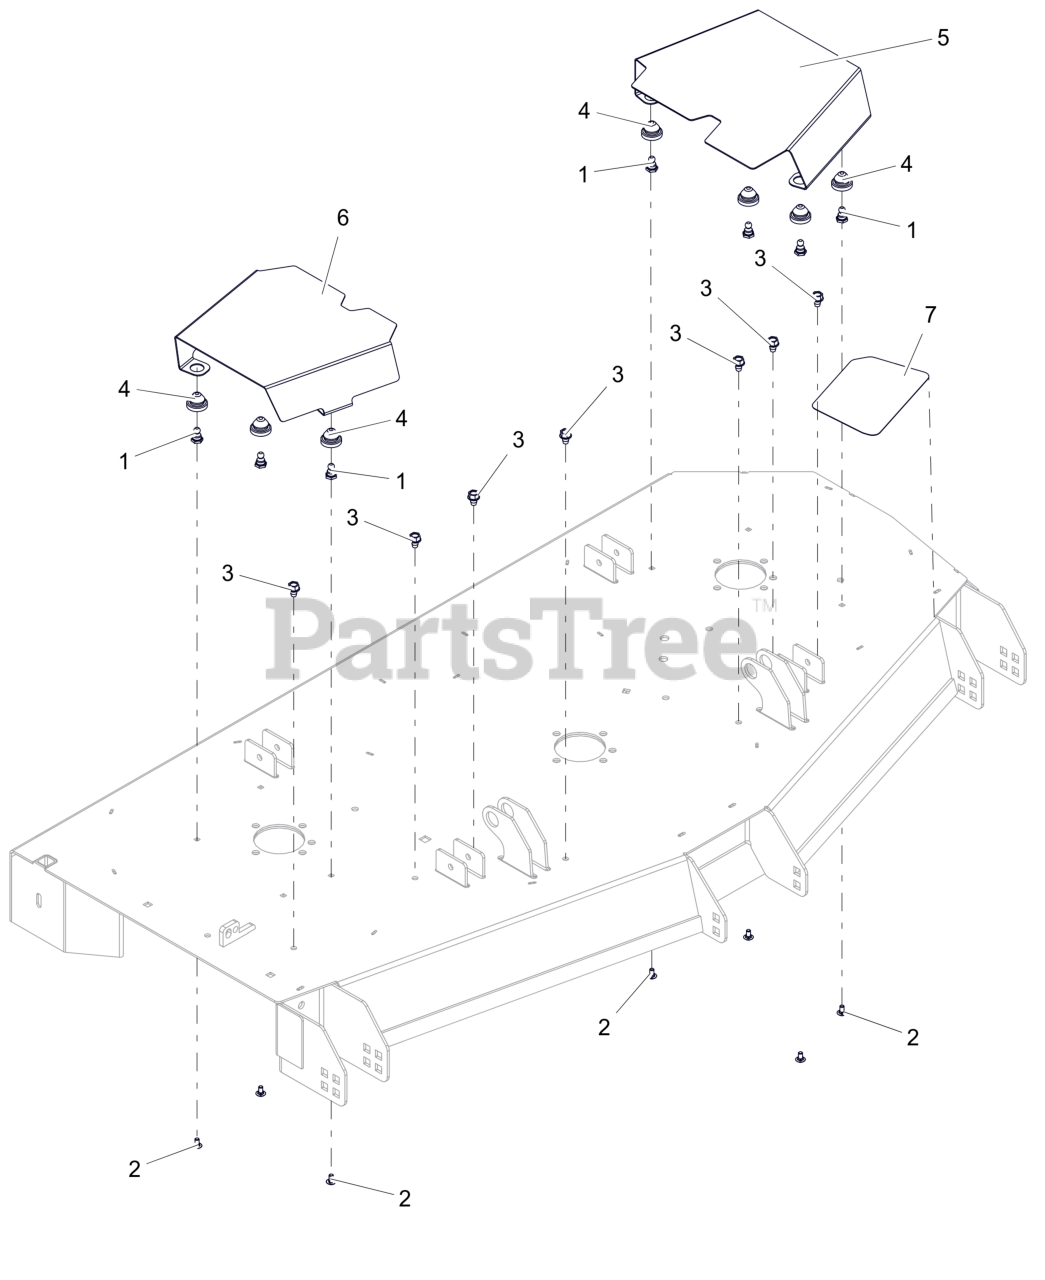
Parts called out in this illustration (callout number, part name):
1	STUD, BALL FEMALE .250-20 THREAD
2	BLT, RHSSN.25-20X.500 G5 ZCC
3	SCR,TAP .375-16X.50 HWH TR ZCC
4	COUPLING, RUBBER PUSH-IN
5	COVER- BELT 60" LEFT
6	COVER- BELT 60" RIGHT
7	GRIP, STEP ANTI SKID HD XF3
